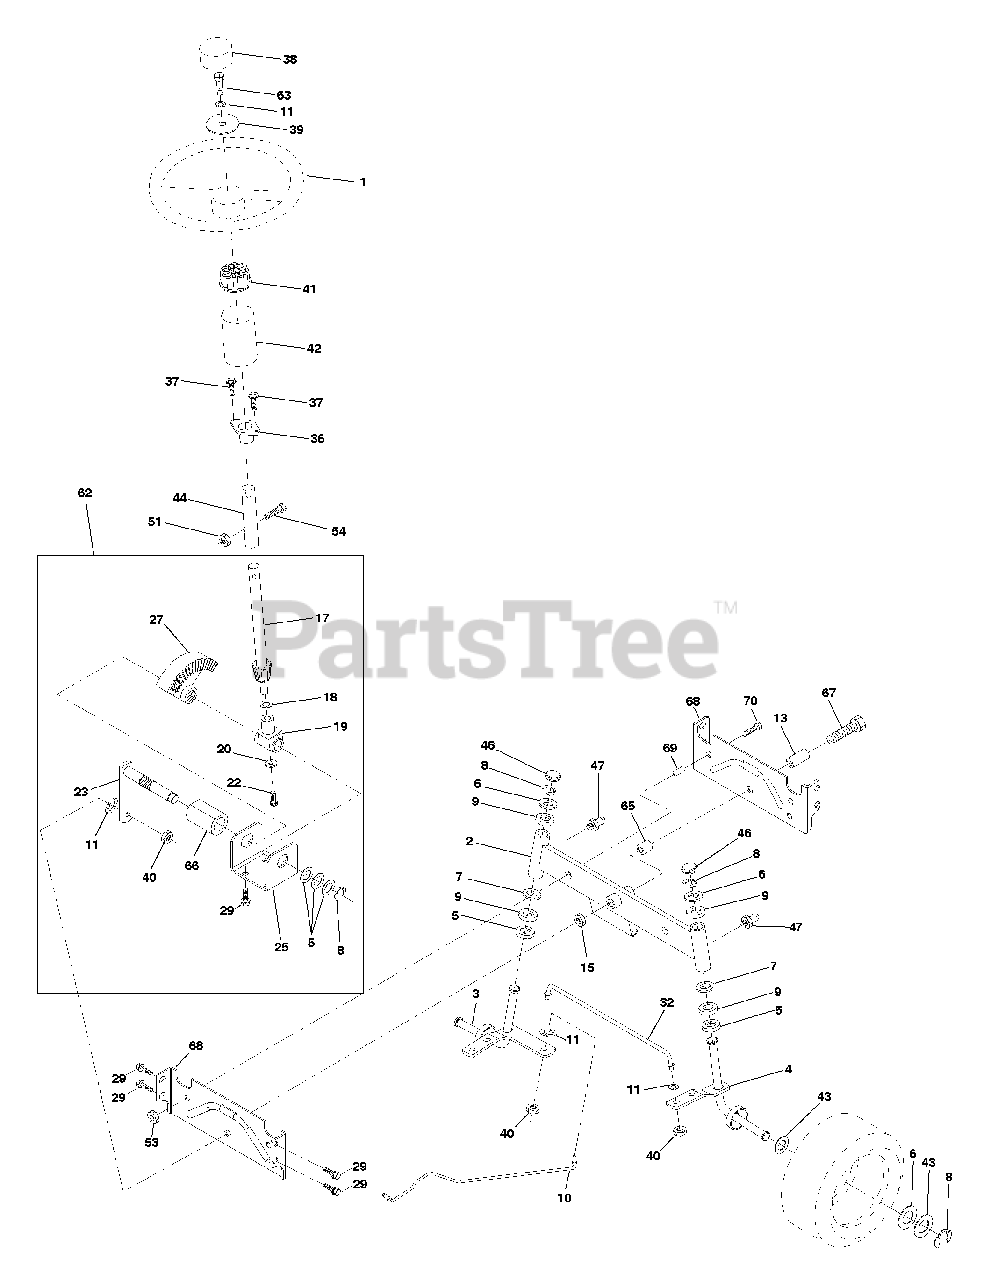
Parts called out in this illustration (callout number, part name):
1	Wheel Steering
2	Axle Front Casting Machined
3	Spindle Asm LH
4	Spindle Asm RH
5	Bearing Race Thrust Harden
6	Washer 25/32 X 1-5/8 X 16 Ga
7	Washer 27/32 X 1-1/4 X 16 Ga
8	Ring Klip #t5304-75
9	Bearing Col Strg Blk
10	Link Drag Extended Cast
11	Washer Lock Hvy Hlcl Spr 3/8
13	Bearing Axle STLT/GT
15	Nut Lock Flange 5/8-11 Unc
17	Shaft Asm Strg
18	Washer Thrust 515 x 750 x 033
19	Support Shaft
20	Washer Shim 1/4 X 5/8 X 062
22	Screw Cap Sckt Hd Phos & Oil
23	Shaft Asm Pittman
25	Bracket Steering
26	Bushing Link Drag Blk LR
27	Gear Sector
28	Washer 13/32 X 7/8 X 16 Ga
29	Screw Thdrol 3/8-16 x 3/4 Ty-tt
30	Pin Cotter 1/8 X 3/4 Cad
32	Rod Asm Tie Ball
36	Bushing Strg
38	Insert Cap Strg Wh Au
39	Washer 13/32 X 2-3/8 X 8 Ga
40	Lock nut
41	Adaptor Wheel Strg
42	Boot Steering Shaft
43	Washer 25/32 X 1 1/4 X 16 Ga
44	Extension Steering Shaft LR/LT
46	Cap Spindle Fr Top Blk
47	Fitting Grease
51	Nut Lock Hex w/Ins 5/16-18
53	Nut Crownlock 3/8-16 unc
54	Bolt Fin Hex 5/16-18 Unc x 1-1/4
62	Kit, Steering Assembly Svc
63	Bolt Fin Hex 3/8-16 unc x 1 Gr. 5
65	Spacer Axle
66	Bearing Arm Pittman
67	Bolt, Fin Hex 5/8-11 UNC x 2-3/4
68	Axle, Brace
69	Spacer Brace Axle
70	Bolt Fin Hex 3/8-16 unc x 2-1/4
